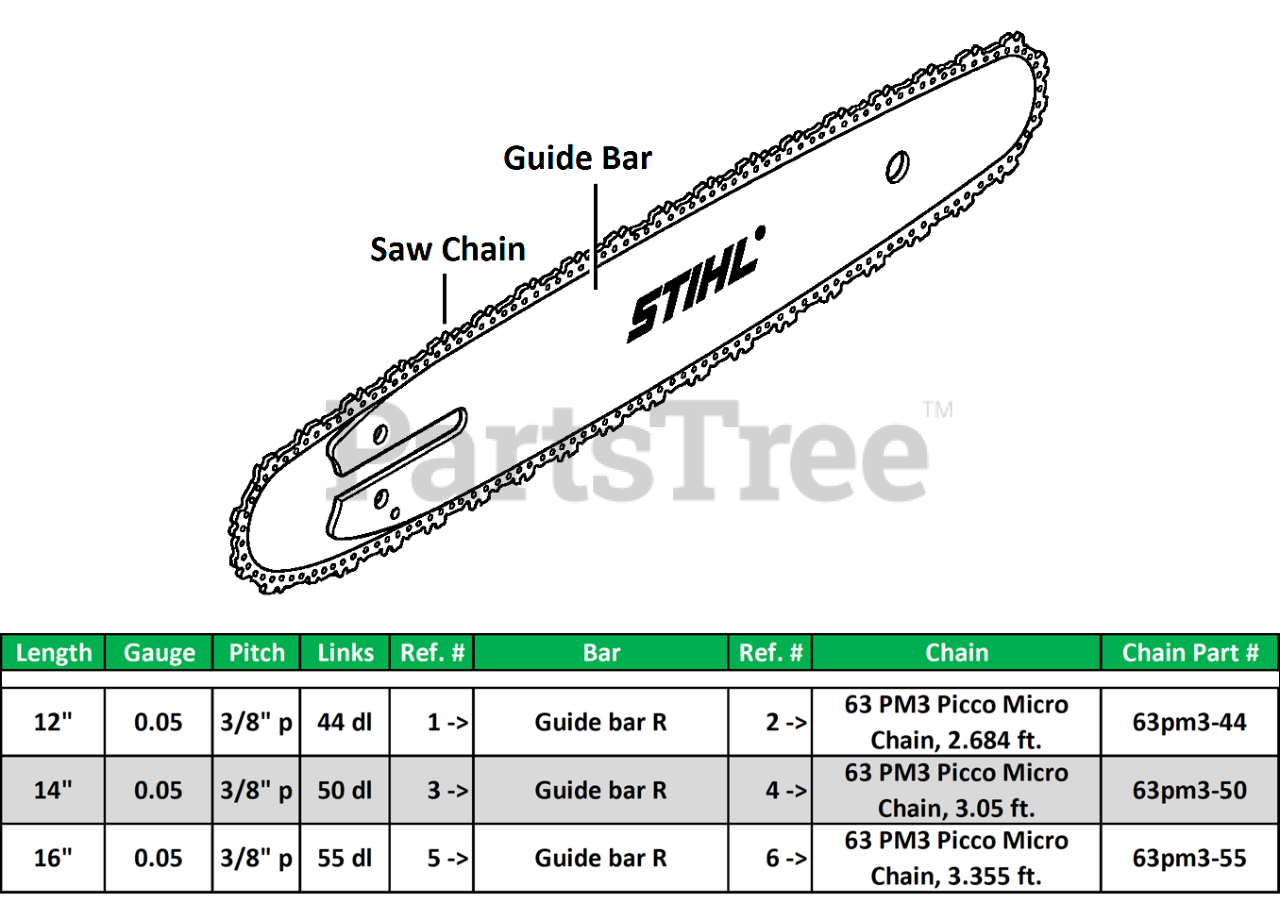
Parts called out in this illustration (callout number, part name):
1	Guide bar R 30cm/12" 1,3mm/0.050" 3/8" P
2	63 PM3 Picco Micro Chain, 2.684 ft.
3	Guide bar R 35cm/14" 1,3mm/0.050" 3/8" P
4	63 PM3 Picco Micro Chain, 3.05 ft.
5	Guide bar R 40cm/16" 1,3mm/0.050" 3/8" P
6	63 PM3 Picco Micro Chain, 3.355 ft.
